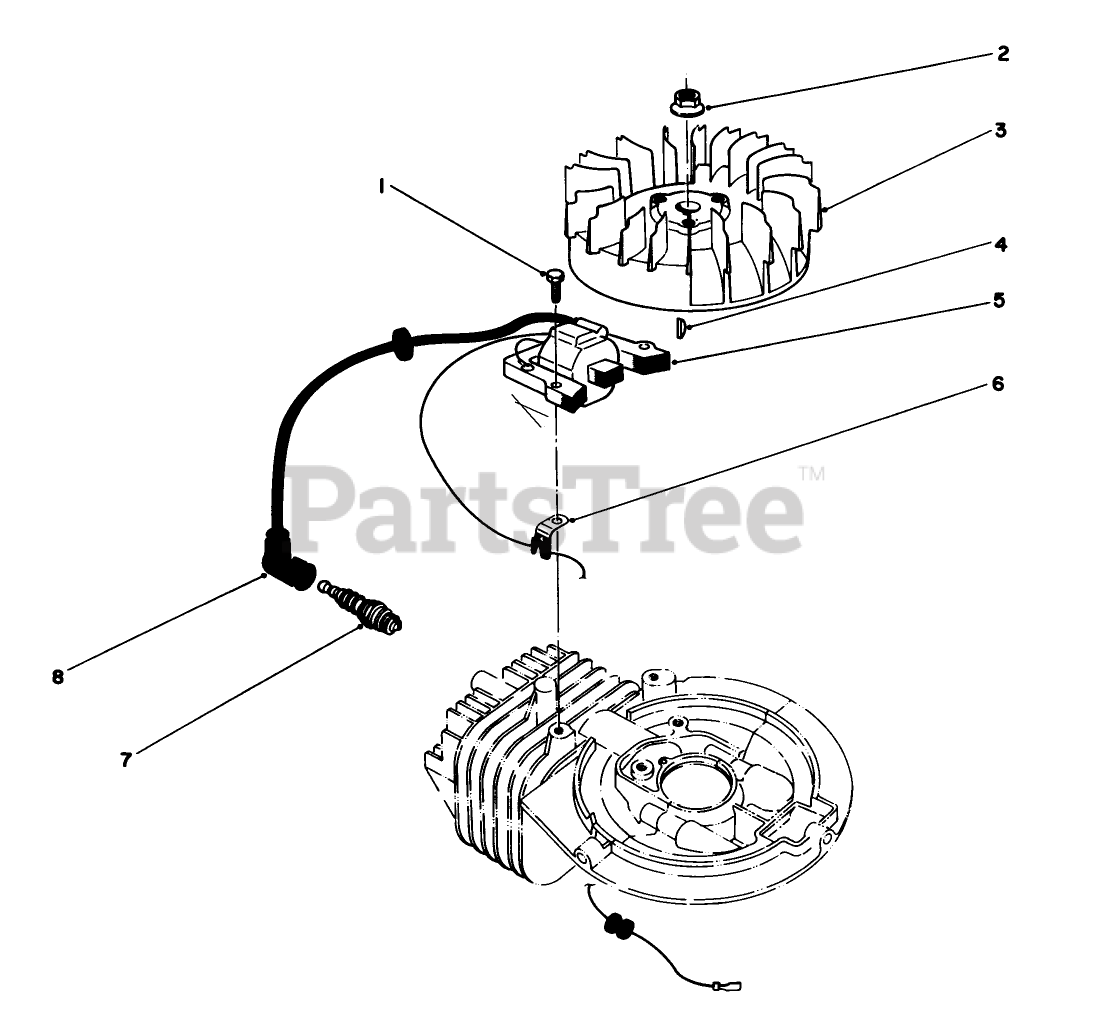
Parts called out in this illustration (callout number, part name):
1	SCREW
3	FLYWHEEL
5	COIL-MAGNETO
6	CLAMP
7	SPARK PLUG
8	CAP-SPARKPLUG
